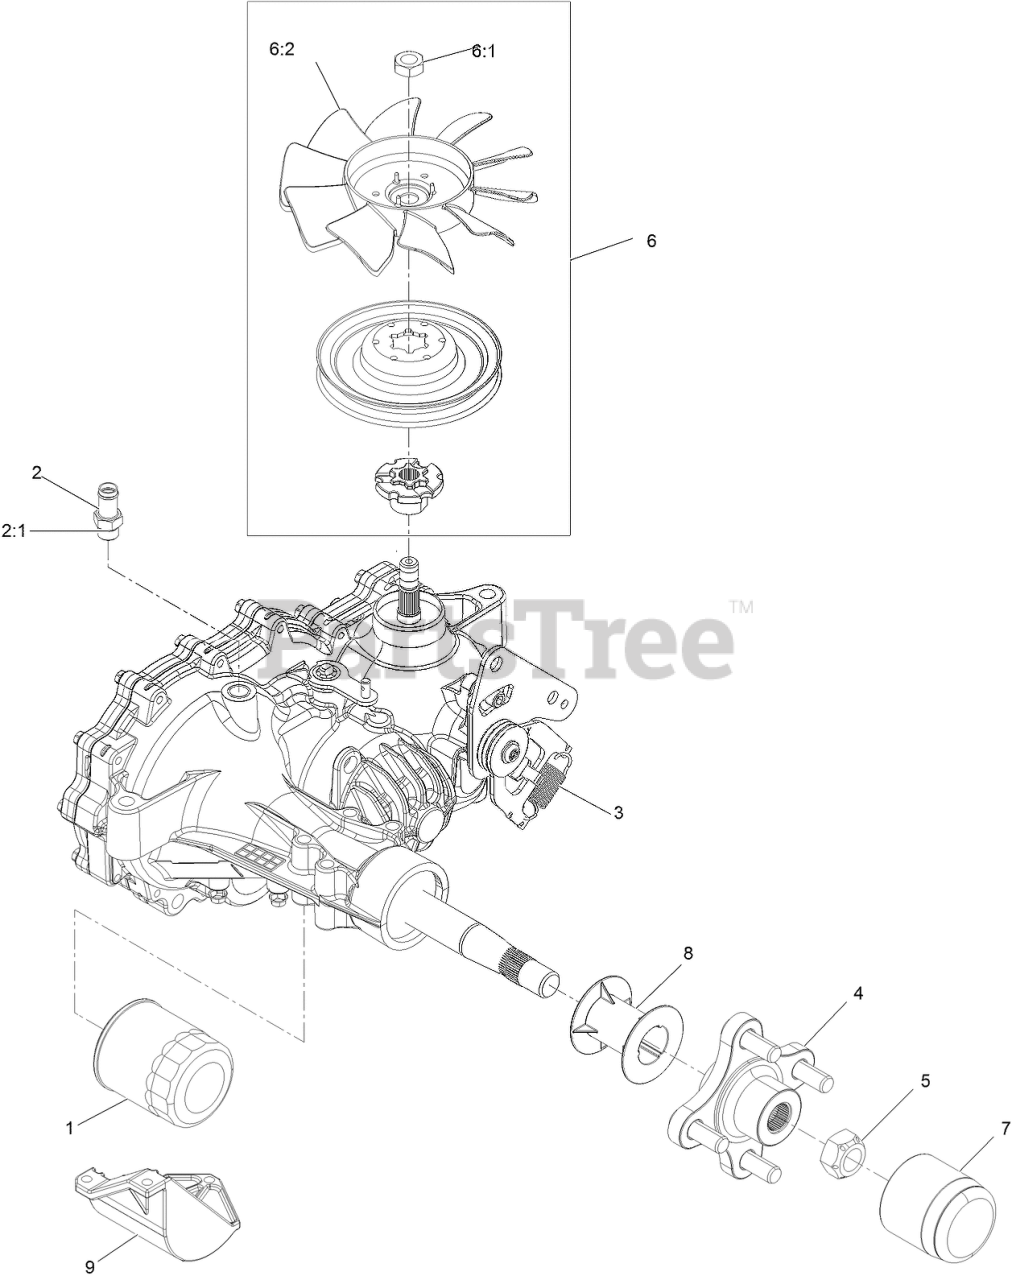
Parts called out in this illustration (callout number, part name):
1	ELEMENT-OIL FILTER, HYD
2	ADAPTER-STRAIGHT
2:1	O-RING
3	SPRING-EXTENSION
4	HUB-OFFSET
5	NUT-HUB
6	Fan And Pulley Kit
7	CAP-AXLE, LONG
8	TUBE-AXLE
9	GUARD-FILTER, RH
99	SEAL KIT
99	BRAKE SHAFT SEAL KIT
